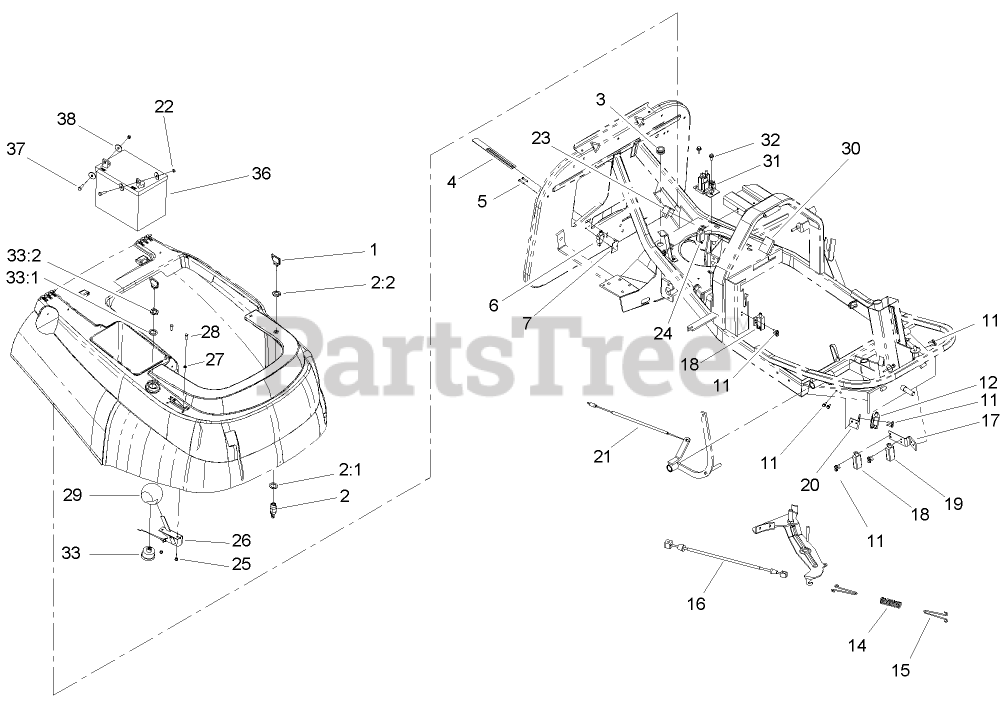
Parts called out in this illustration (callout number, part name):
1	KEY-IGNITION
2	STARTER SWITCH ASM
2:1	WASHER-LOCK
2:2	NUT-HH
3	Grommet
4	Lever-Bag Fill
6	Switch
7	Clamp-Bag Fill
11	SCREW-HH, TAP
14	Spring-Compression
15	Hook-Spring
17	Bracket-Switch
20	Bracket-Switch
21	CABLE-BRAKE
22	NUT-HEX
23	RELAY
25	NUT-LOCK
26	Throttle Cable ASM
27	WASHER
28	SCREW-HH
30	MODULE
32	SCREW-HHF, TAP
33:1	WASHER-LOCK
33:2	NUT-HH
37	SCREW-HH
38	Washer-Flat
